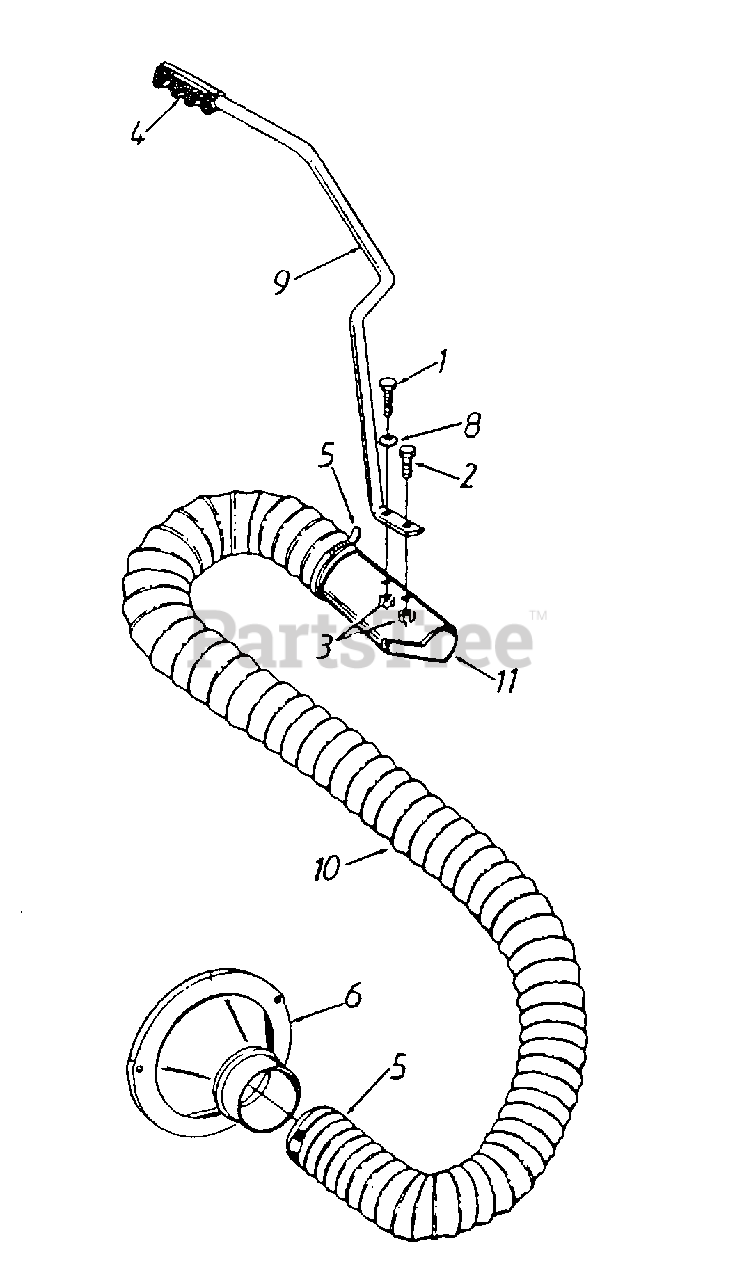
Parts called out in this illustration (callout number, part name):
1	Hex Bolt 1/4-20 x 1.25" Lg.
2	Hex Bolt 1/4-20 x .62" Lg.
3	Hex L-Nut 1/4-20 Thd.
5	Adj. Hose Clamp 5" Dia.
6	Hose Adapter
8	Saddle Washer .32" I.D.
10	Hose-5" Dia.
11	Nozzle Tube
